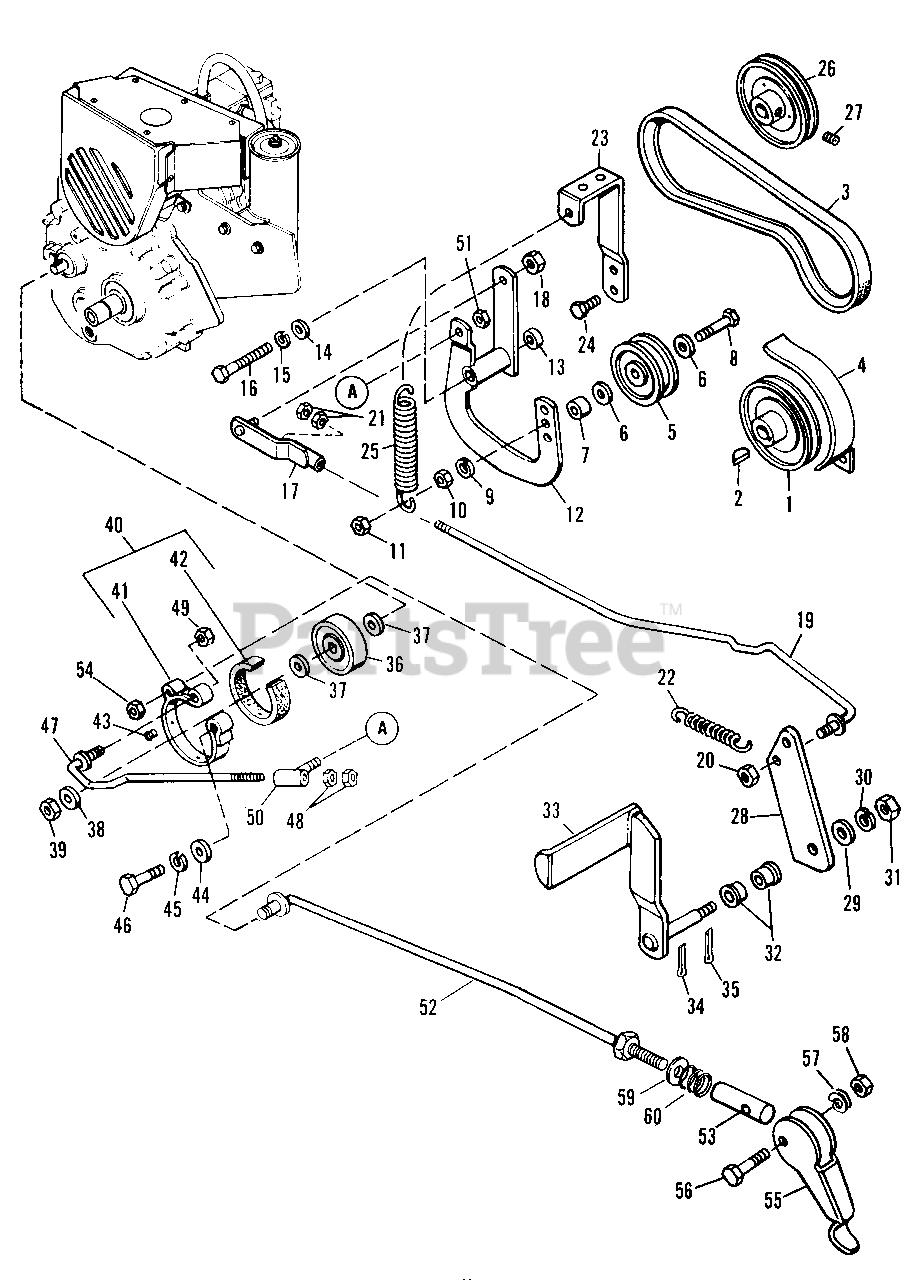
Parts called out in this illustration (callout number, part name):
1	Driver Pulley
2	Woodruff Key, 3/16" x 3/4"
3	BELT, A-Sect, 47.30
4	Belt Guard Assy.
5	Idler Pulley
6	Plain Washer, 3/8"
8	Hex Cap Screw, 3/8"-16 x 2-1/4"
9	Lock Washer, 3/8"
10	Full Hex Nut, 3/8"-16
11	Jam Hex Lock Nut, 3/8"-16
12	Idler Lever Assy.
14	Plain Washer, 3/8"
15	Lock Washer, 3/8"
16	Hex Cap Screw, 7/16"-14 x 3-3/4"
17	Rod Guide Assembly
18	Full Hex Lock Nut, 5/16"-18
19	Clutch Rod Assy.
20	Hex Nut, Full, Lock, 5/16"-18
21	Full Hex Nut, 5/16"-18
22	Front Tension Spring
23	Spring Bracket, 1/4" x 1 x 11-1/4"
24	Hex Hd. Cap Screw, 3/8" x 3/4"
25	Idler Pulley Spring
26	Driven Pulley
27	Cup Pt. Socket Hd. Set Screw, 5/16"-18 x 5/16"
28	Foot Pedal Arm, 1/4" x 1-3/4" x 5-7/8"
29	Plain Washer, 3/8"
30	Lock Washer, 3/8"
31	Full Hex Nut, 3/8"-16
33	Foot Pedal Assy.
34	Cotter Pin, 3/32" x 3/4"
35	Cotter Pin, 1/8" x 3/4"
38	Plain Washer, 3/8"
39	Lock Nut, 7/16"-14
40	Brake Band & Lining Assy.
42	Brake Lining
43	Rivet No. 7 x 1/4"
44	Plain Washer, 5/16"
45	Lock Washer, 3/8"
46	Hex Cap Screw, 3/8"-16 x 1-3/4"
47	Brake Rod Assy.
48	Full Hex. Nut, 3/8"-16
49	Full Hex Lock Nut, 3/8"-16
50	Rod Guide Assy.
51	Full Hex Lock Nut, 5/16"-18 N.C.
52	Parking Brake Rod Assy.
54	Full Hex Nut, 5/16"-18
55	Parking Brake Lever
56	Hex Cap Screw, 1/4"-20 x 1-1/4" Grade 8
57	Double Lock Washer, 1/4"
58	Hex Nut, Full, Lock 1/4"-20
59	Plain Washer, 1/2"
